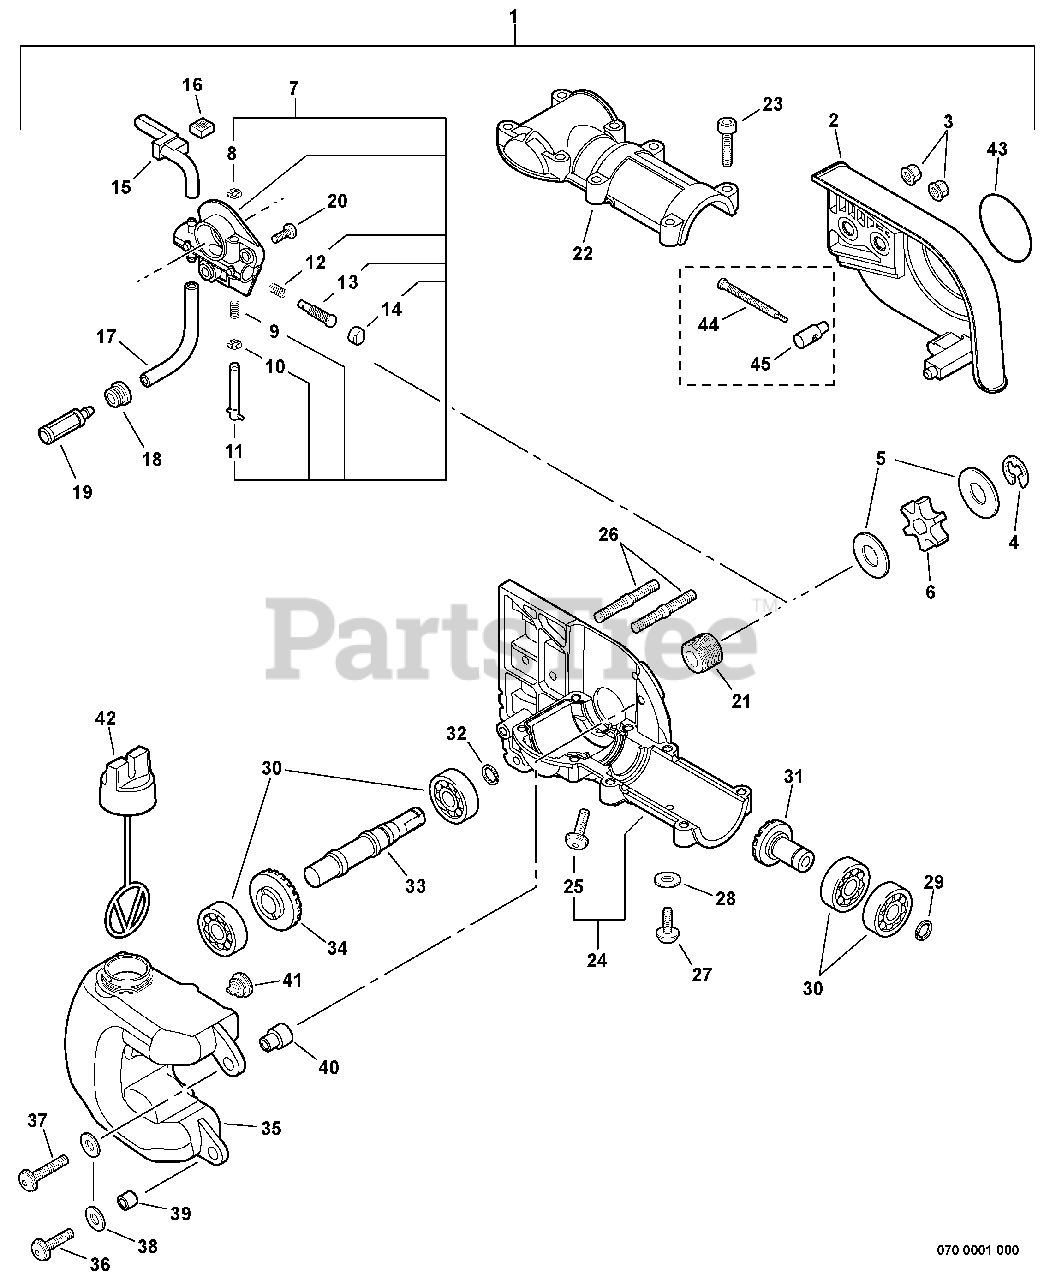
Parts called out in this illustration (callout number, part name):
1	AUTO OILER/GEAR CASE ASSY
2	GUARD, SPROCKET
3	NUT, FLANGE M6
4	RING, RETAINING Ø0.300
5	WASHER 10.2×24.5×1.2
6	SPROCKET, DRIVE
7	AUTO-OILER ASSY
11	ADJUSTER, OILER
13	PLUNGER ASSY
14	CAP, OIL PUMP
15	PIPE, OIL OUTLET
16	PAD, FOAM
17	PIPE, IMPULSE 3×6×75
18	GROMMET
19	FILTER, OIL
20	BOLT 5×10
21	GEAR, WORM
22	COVER, GEAR CASE
23	BOLT 5×0.8×25
24	CASE, GEAR - LOWER
25	BOLT 5×10
26	BOLT, STUD 6
27	BOLT 5×10
28	WASHER, FLAT 5.5×10×0.8
29	RING, SNAP Ø12
30	BEARING, BALL
31	GEAR, BEVEL
32	RING, SNAP Ø12
33	SHAFT, GEAR
34	GEAR, BEVEL - 23 TOOTH
35	TANK, OIL
36	BOLT 5×16
37	BOLT 5×0.8×25
38	WASHER 5.5×12×0.8
39	SPACER 6.2×7.8×6
40	COLLAR 6
41	VENT ASSY
42	CAP ASSY, OIL
43	LABEL, ECHO
44	BOLT 5
45	TENSIONER, CHAIN
